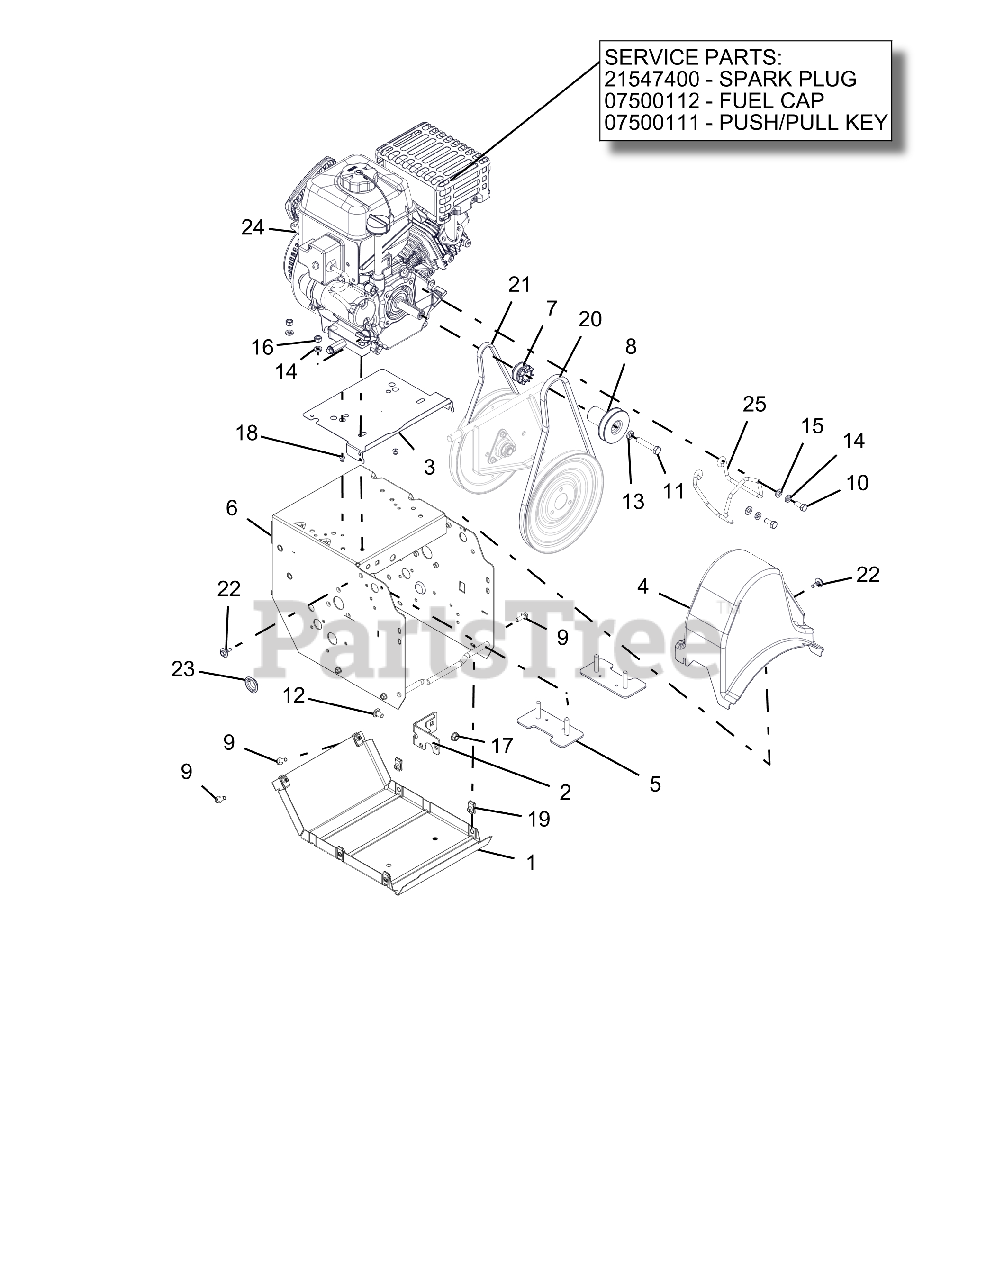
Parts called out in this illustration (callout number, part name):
1	COVER, BOTTOM
2	WELDMENT, FRAME BRACKET
3	BAFFLE,ENGINE,SMALL BLOCK
4	COVER, COMPACT BELT
5	STRAP, ENGINE BOLT-WELDMENT
6	WELDMENT,FRAME 920
7	SHEAVE, TRACTION
8	SHEAVE,AUGER 3/4" PM
9	BLT-HEX .25-20X.75 HWH YZ GR5
10	BLT-HEX .31-24X.75 YWZC GR5
11	BLT-HEX .38-24X2.0 YWZC
12	@BLT-RHDSSQNK .31-18X.62 G5YZ
13	WSHR-LK .375X.115 HVY YWZC
14	WSHR-LK .312X.097 HVY YWZC
15	@WSHR-FL-STL.344X.688X.065YWZC
16	@NUT-HEX .31-18 YWZC
17	@NUT-LK-TOP-FLG .31-18 YWZC
18	RVT-POP .187 YZ
19	NUT-RTNR .25-20X.56
20	V-BELT, HA-RAW EDGE
21	V-BELT, 3L-WRAPPED
22	SCR-TAP .25-20X.5 CAPTIVE
23	PLUG, HOLE - 1.00" FLEXTEMP
24	ENGINE, SNO-TEK 208 240V
24	PLUG, SPARK
24	CAP, FUEL TANK BLACK
24	KEY, PUSH/PULL LCT (2/PACKAGE)
25	FINGER, BELT
